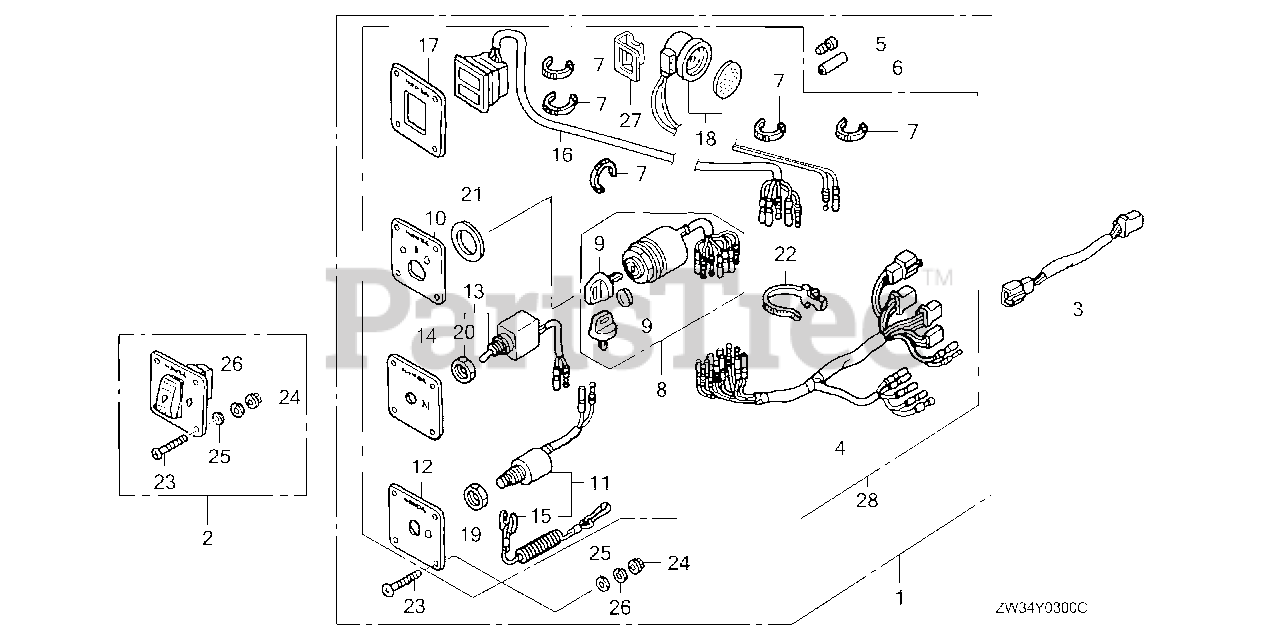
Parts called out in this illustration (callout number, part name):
2	SWITCH KIT, LIGHT
3	SUB-HARNESS ASSY., POWER TRIM-TILT (A)
23	SCREW, PAN (5X40)
24	NUT, FLANGE (5MM)
25	WASHER, PLAIN (5MM)
26	WASHER, SPRING (5MM)
